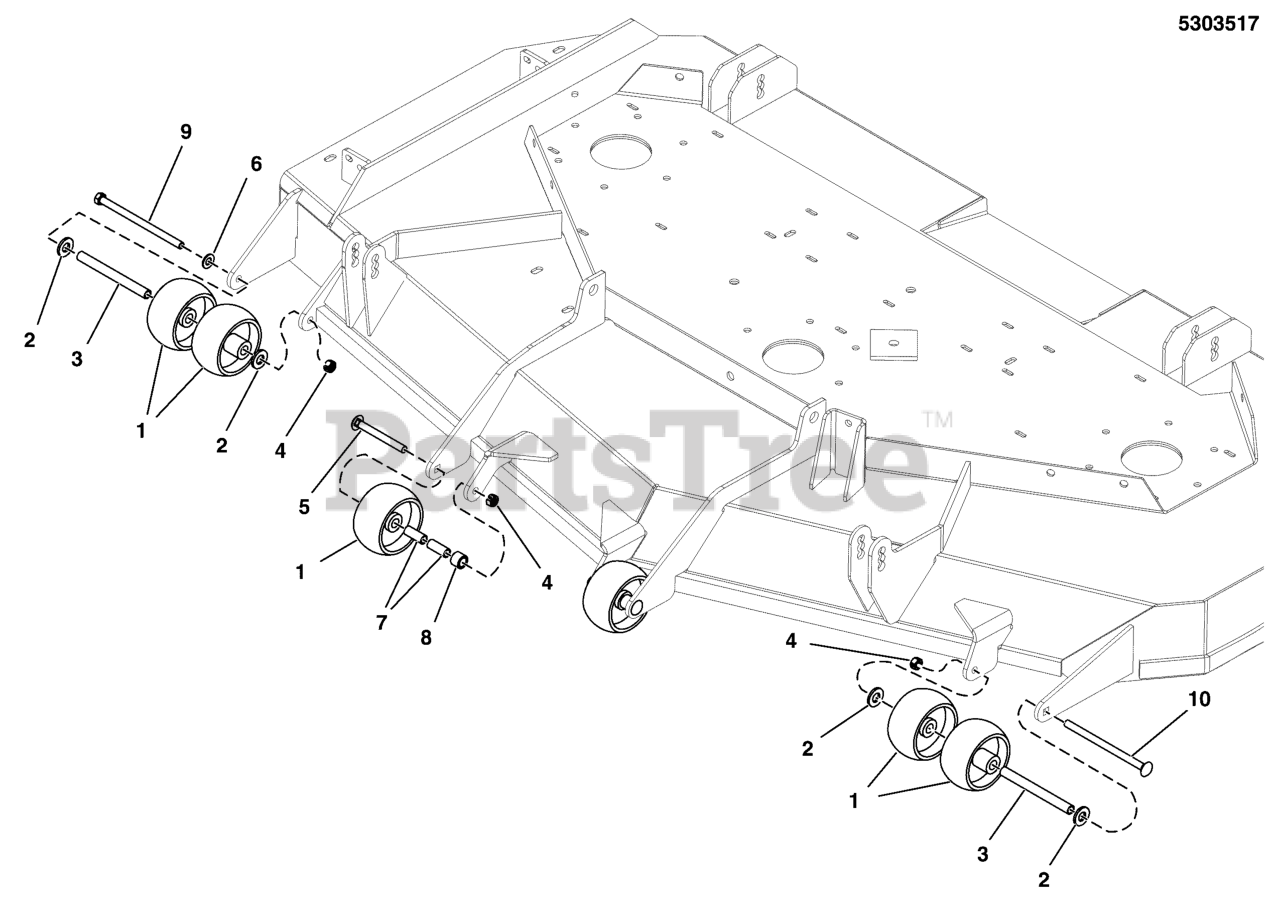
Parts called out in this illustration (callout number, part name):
1	WHEEL- 2.00 WIDE 3.88 DIA 0.531ID POLY
2	WASHER, 1/2 GD9 CZ
3	SPACER, .38 X .50 X 5.06, CZ
4	NUT, 3/8-16 HEX SIDE LOCK
5	BOLT, 3/8-16 X 3-1/2, CARRIAGE, GD5, CZ
6	WASHER, 3/8 SAE
7	SPACER, .38 X .50 X 1.25, CZ
8	SPACER, .51 X .75 X .56, PM, CZ
9	BOLT, 3/8-16 X 6" GD5 CZ
10	BOLT, 3/8-16 X 6, CARRIAGE, GD5, CZ
